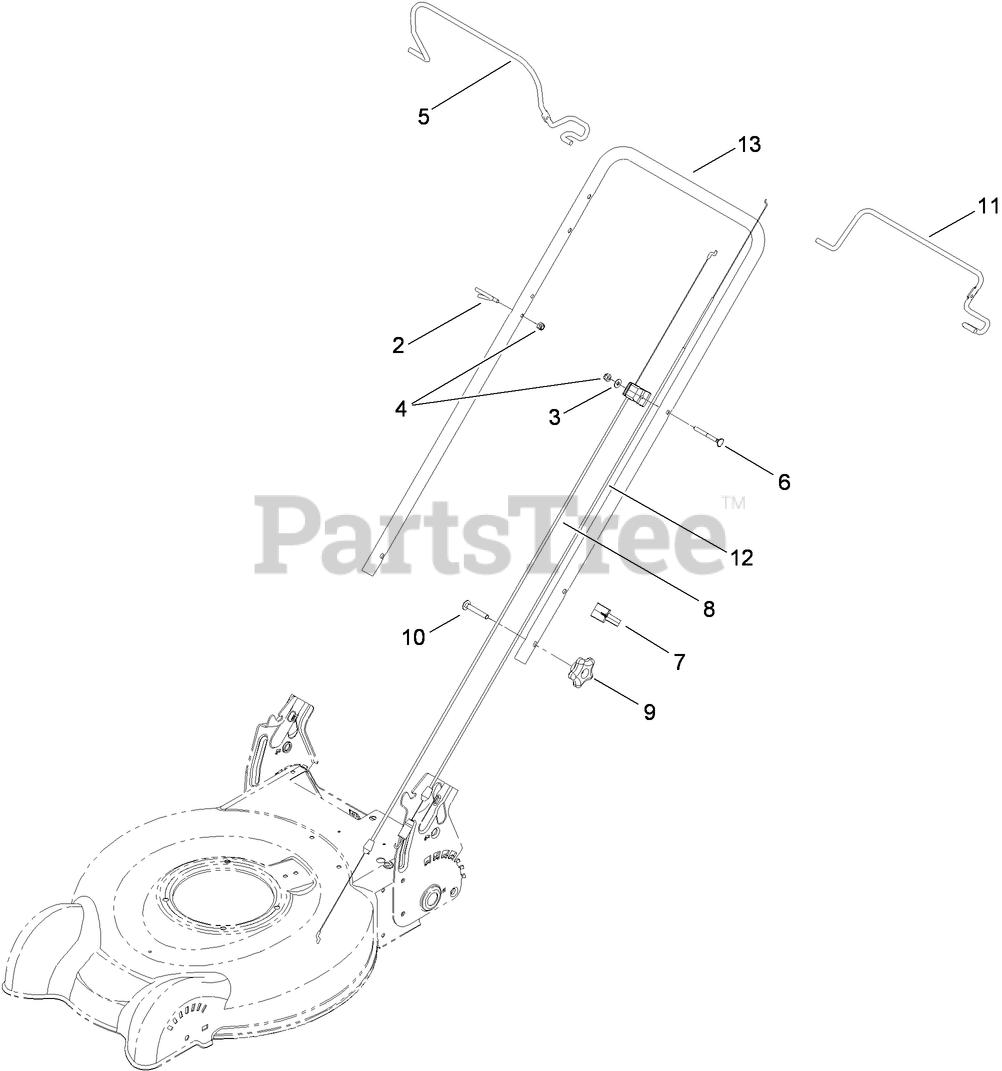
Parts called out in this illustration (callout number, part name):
2	GUIDE-ROPE
3	WASHER-FLAT
4	NUT-LOCK, NI
5	BAIL-BRAKE
6	SCREW-HANDLE
7	GUIDE-CABLE
8	CABLE-BRAKE
9	KNOB-HANDLE
10	Screw-CARR
11	BAIL-TRACTION, 2-BAIL FLAT
12	CABLE-TRACTION
13	HANDLE-UPPER
